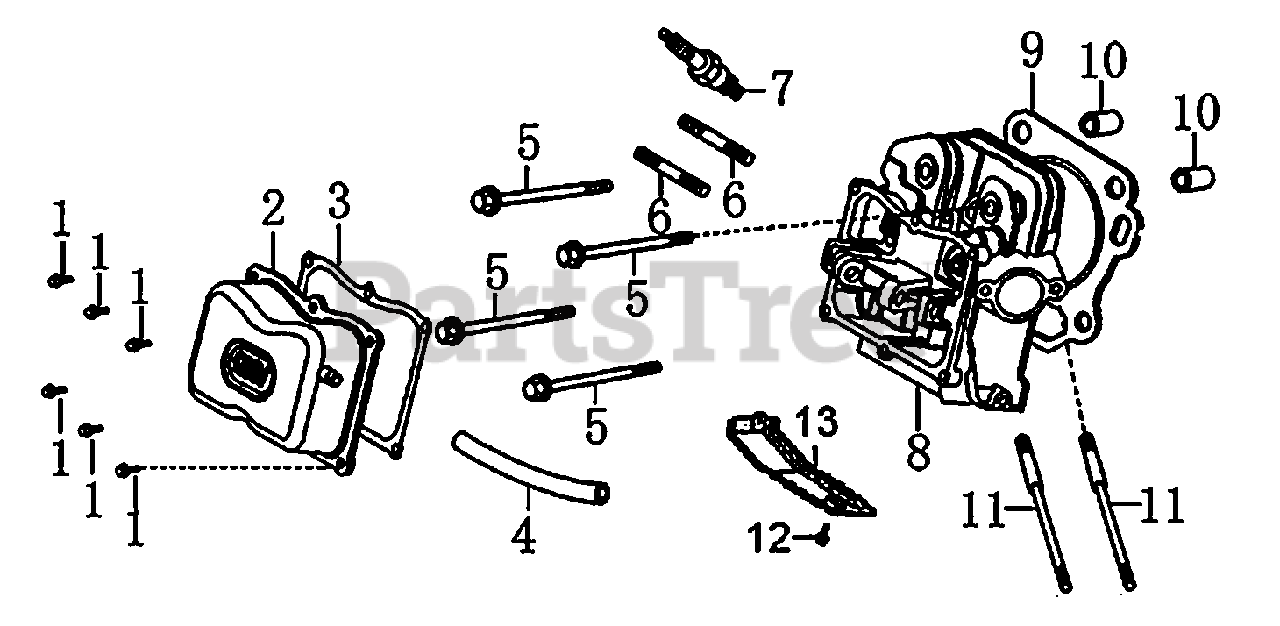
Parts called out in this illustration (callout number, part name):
1	BOLT, FLANGE
2	COVER, HEAD
3	GASKET, HEAD COVER
4	TUBE, BREATHER
5	BOLT, FLANGE, 10X80
6	BOLT, STUD, EXHAUST
7	SPARK PLUG
8	CYLINDER HEAD
9	GASKET, CYLINDER
10	DOWEL, PIN
11	BOLT, STUD, INTAKE
12	BOLT, FLANGE M6X12
